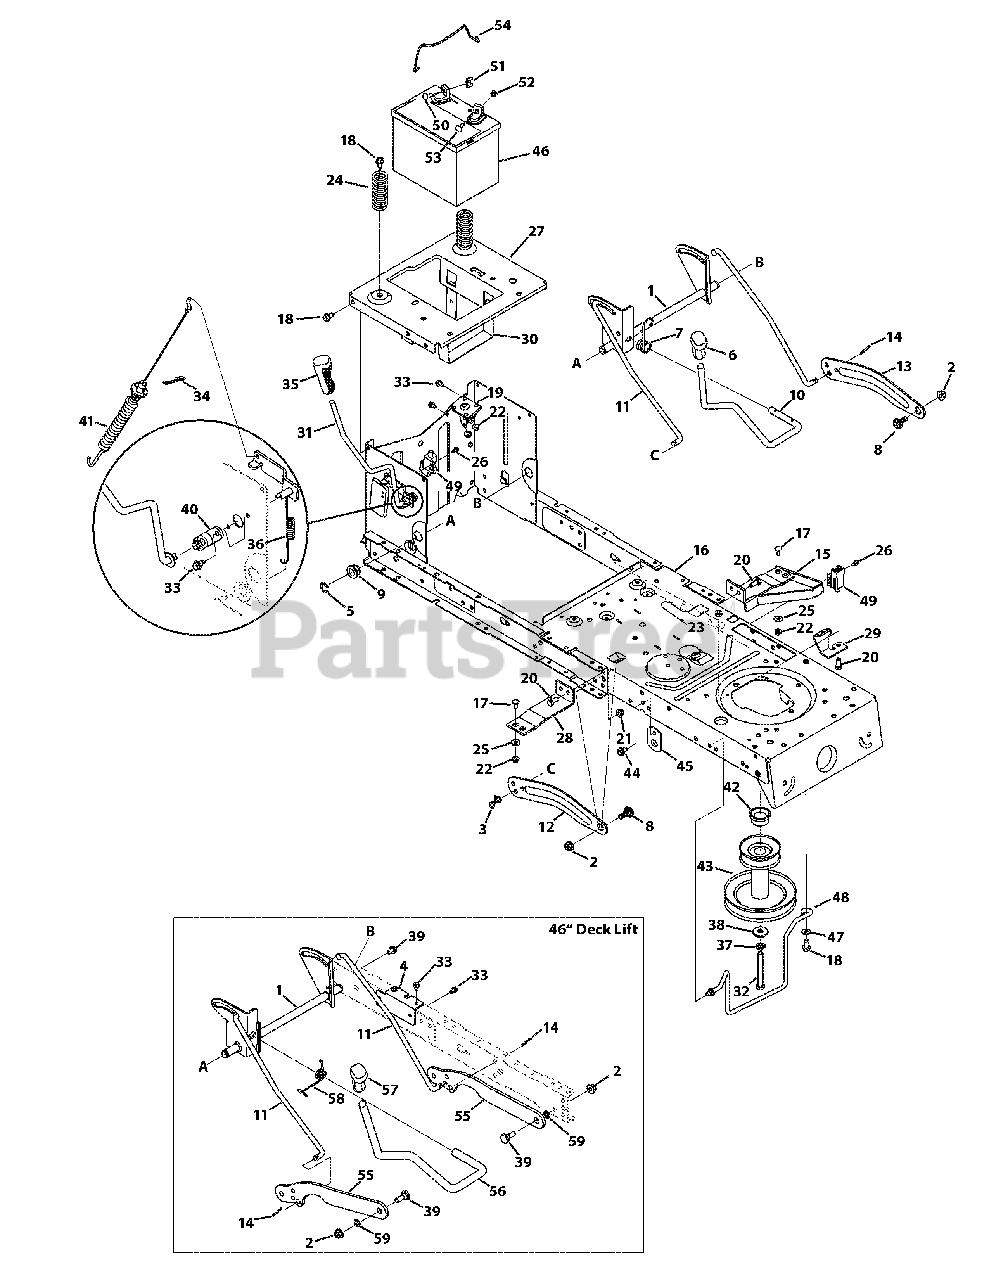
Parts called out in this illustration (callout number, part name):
1	Shaft Assembly Lift 42"
1	Deck Shaft Assembly Lift 46" Deck
2	Nut, Flange Lock, 3/8-16, GrF
3	Pin, Cotter .08 x 1.56 Intern. RH
4	Frame Brace Bracket
5	Ring, E-Type, .625 Dia.
6	Grip, Handle, 1/2
7	Spring, Torsion 42" Deck
8	Screw, Shoulder, .625 x .175, 3/8-16
9	Bearing, Hex Flange
10	Deck Handle, Lift, 42" Deck
11	Rod, Lift
12	Lift Arm, Deck - RH
13	Lift Arm, Deck - LH
14	Cotter Pin
15	Support Bracket Assembly
16	Frame Assembly
17	Carriage Screw, 1/4-20 x .62
18	Screw, 5/16-18, .750
19	Solenoid
20	Hex Screw, 5/16-18 x .75
21	Flange Lock Nut, 5/16-18
22	Nut, Flange Lock, 1/4-20, GrF
23	Hex Lock Nut, 5/16-18
24	Spring, Compr. , 1.28 OD x 3.125
25	Flat Washer, .28 x .74 x .063
26	Shoulder Screw, #10-32 x .500
27	Seat Bracket, Frame
28	Bracket, Runing Board
29	Frame Support Bracket
30	Bracket, Battery
31	Handle Assembly, PTO
32	Screw, 7/16-20, 3.25 42" Deck
32	Screw, 7/16-20, 2.75 46" Deck
33	Screw, 1/4-20, 0.500
34	Pin, Click, .092 x 1.64
35	Grip, Handle, 3/8
36	Spring, Extension
37	Washer, Lock, 7/16
38	Washer, Flat, .450 x 1.250 x .164
39	Bolt, Shldr. .500 x .270 3/8-16
40	Bearing, PTO
41	Cable, Deck Engagement
42	Spacer, 1.010 x 1.400 x .825 (42" Deck.)
43	Engine Pulley, 38" & 42"
43	Deck Engine Pulley, 46" Deck
44	Screw, 5/16-18, 0.625
45	Pedal Support Bracket
46	Battery, 155 CCA
47	Washer, Flat, .406 x .875 x .059
48	Rod, Belt Keeper (42" Deck)
48	Rod, Belt Keeper (46" Deck)
49	Switch, Interlock
50	Shoulder Screw, .250 x .150;1/4-20
51	Wing Nut 1/4-20
52	Nut, Sems, 1/4-20
53	Screw, Carriage, 1/4-20, .75, Gr5
54	Battery Hold Down Rod
55	Deck Lift Link
56	Deck Handle, Lift, 46" Deck
57	Grip, Handle, 5/8
58	Spring, Torsion 46" Deck
59	Washer, Flat, .385 x .62 x .063
